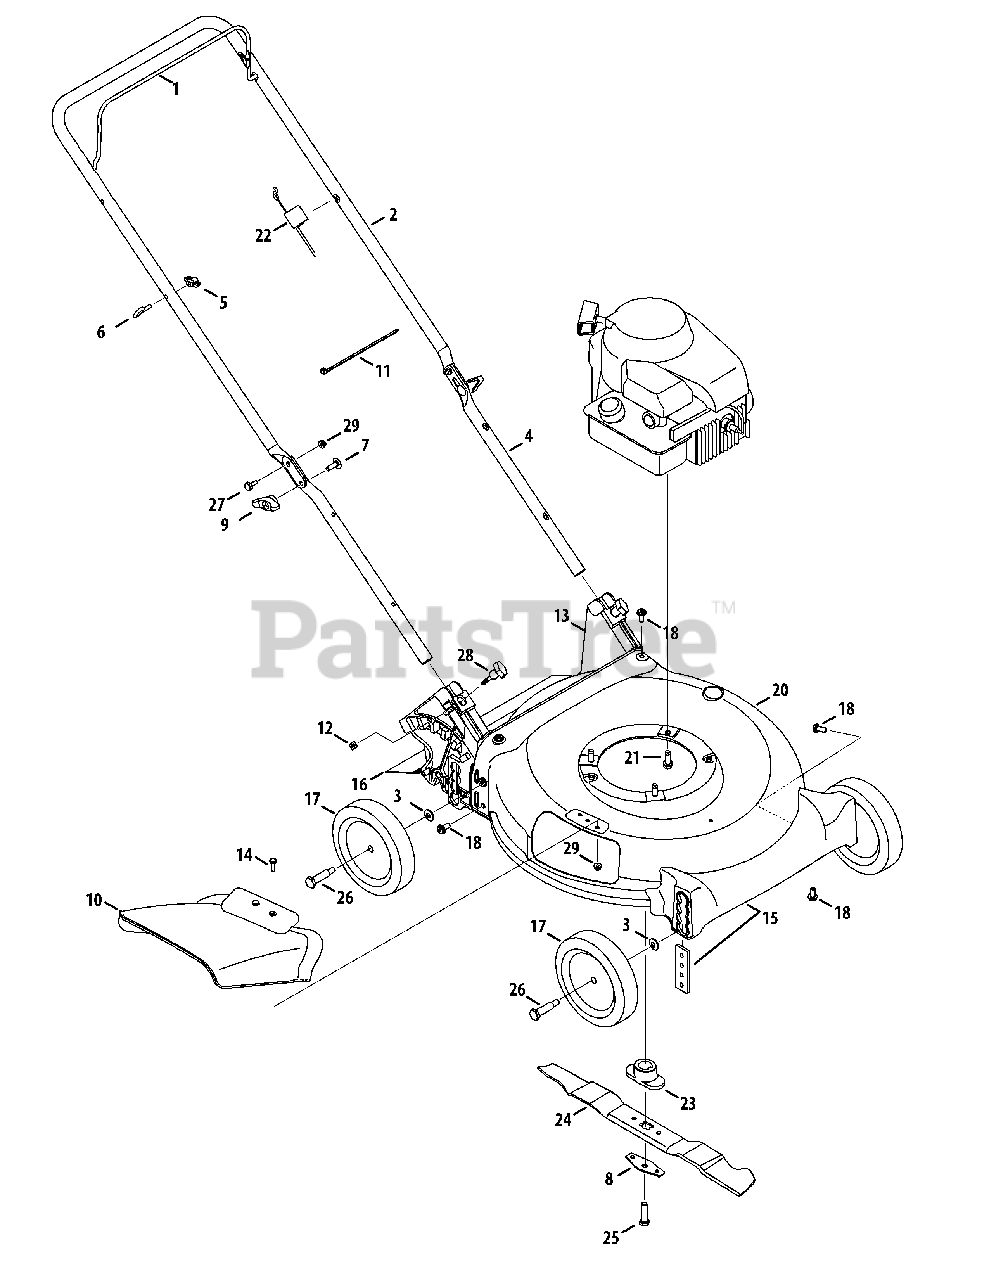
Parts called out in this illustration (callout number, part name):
1	Blade Control Handle - Black
2	Upper Handle - Black (non adjustable)
3	Cupped Washer
4	Lower Handle
6	Rope Guide Bolt
7	Carriage Bolt 5/16-18
8	Blade Bell Support
9	Wing Knob 5/16-18 Red
9	Wing Knob 5/16-18 Black
10	Chute Deflector
12	Sq. Nut 1/4-20
13	Rear Baffle Ass'y
14	Hex. Hd. Cap Screw. 1/4-20 x .75
15	Front Axle Cover
16	Trailing Shield 4.54 x 17.37
17	Wheel Ass'y 7 x 1.5 Diamond Star
18	Hex Hd. Cap Screw. 5/16-14 x .75
21	Hex Wash HD Tap Screw 3/8-16 x .88
22	Control Cable, 158 cc B&S
23	Blade Adapter
24	21" Mulching Blade
25	Hex Bolt 3/8-24 x 1.5" Lg. (Gr 8)
26	Shoulder Screw .498 x 1.6
27	Shoulder Screw .375 x .126 x 1/4-20
28	Knob 1/4-20 x 1.725 Black
28	Knob 1/4-20 x 1.725 Red
29	Flanged Lock Nut 1/4-20 Gr. F Nylon
